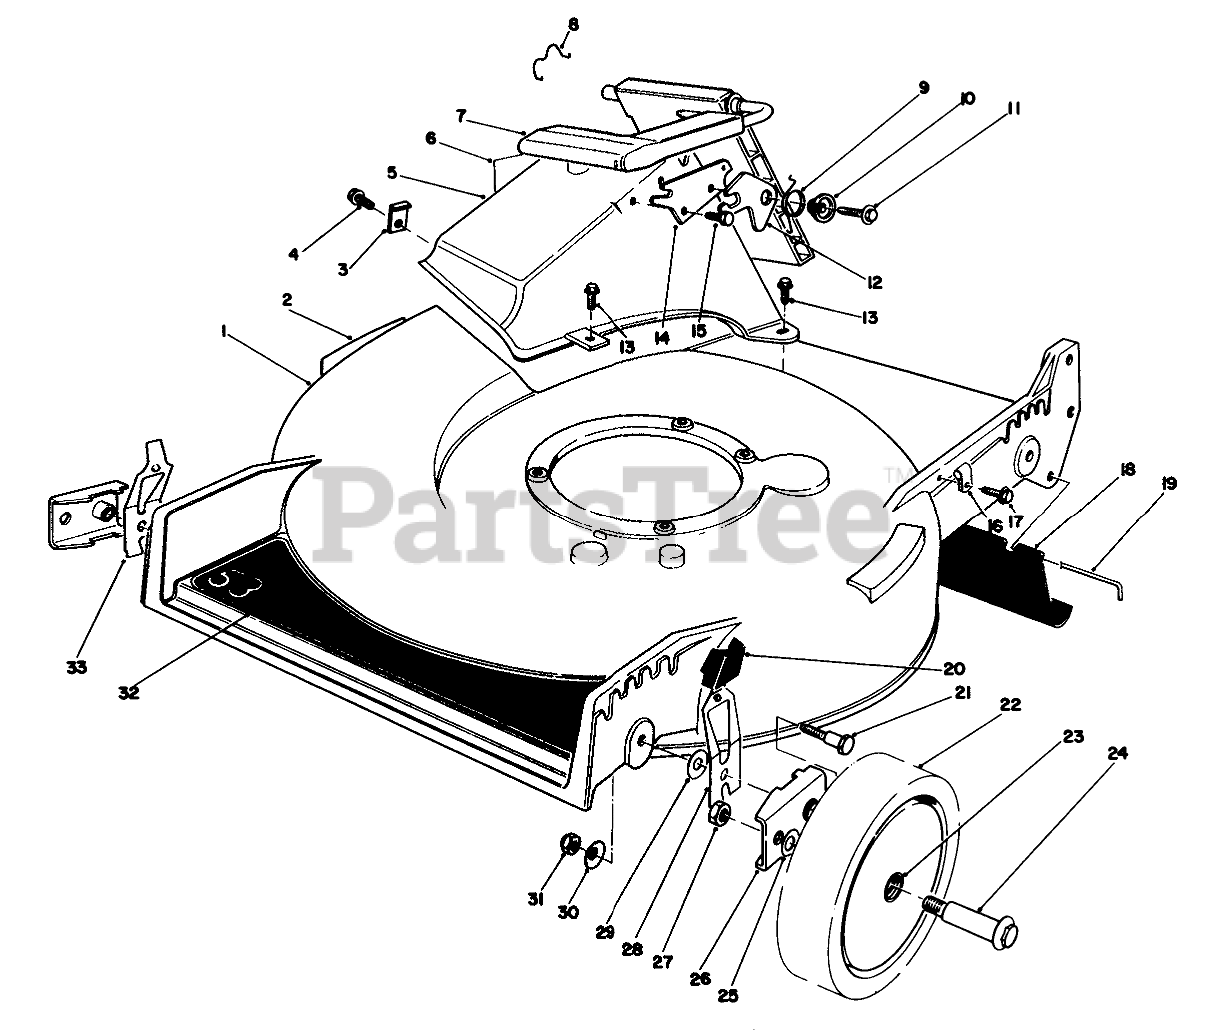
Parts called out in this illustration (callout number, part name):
1	Housing (Incl. Ref. #2)
2	Decal Danger
3	TUNNEL CLIP
4	SCREW
5	Tunnel-Discharge (Incl. Ref. #6)
6	DECAL - DANGER
7	Discharge Door Assembly
8	DOOR RET SPRING
9	TORSION SPRING
10	DOOR SPACER
11	SCREW-HWH
12	SAFETY LATCH
13	SCREW-HWH
14	DOOR LATCH PLATE
15	SCREW-PLASTITE
16	CLAMP-CABLE
17	SCREW
18	SHIELD-TRAILING
19	ROD-SHIELD
20	KNOB-ARM
21	PIVOT SCREW
22	Wheel & Tire Assembly (Inc. Ref. #23)
23	BUSHING
24	BOLT-WHEEL
25	WASHER
26	HP PIVOT ARM ASM
27	Nut
28	L. HP SPRING ARM ASM
29	WASHER-PIVOT
30	WASHER-BELLEVILLE
31	NUT-LOCK, NI
32	Decal-53
33	R HP SPRING ARM ASM
